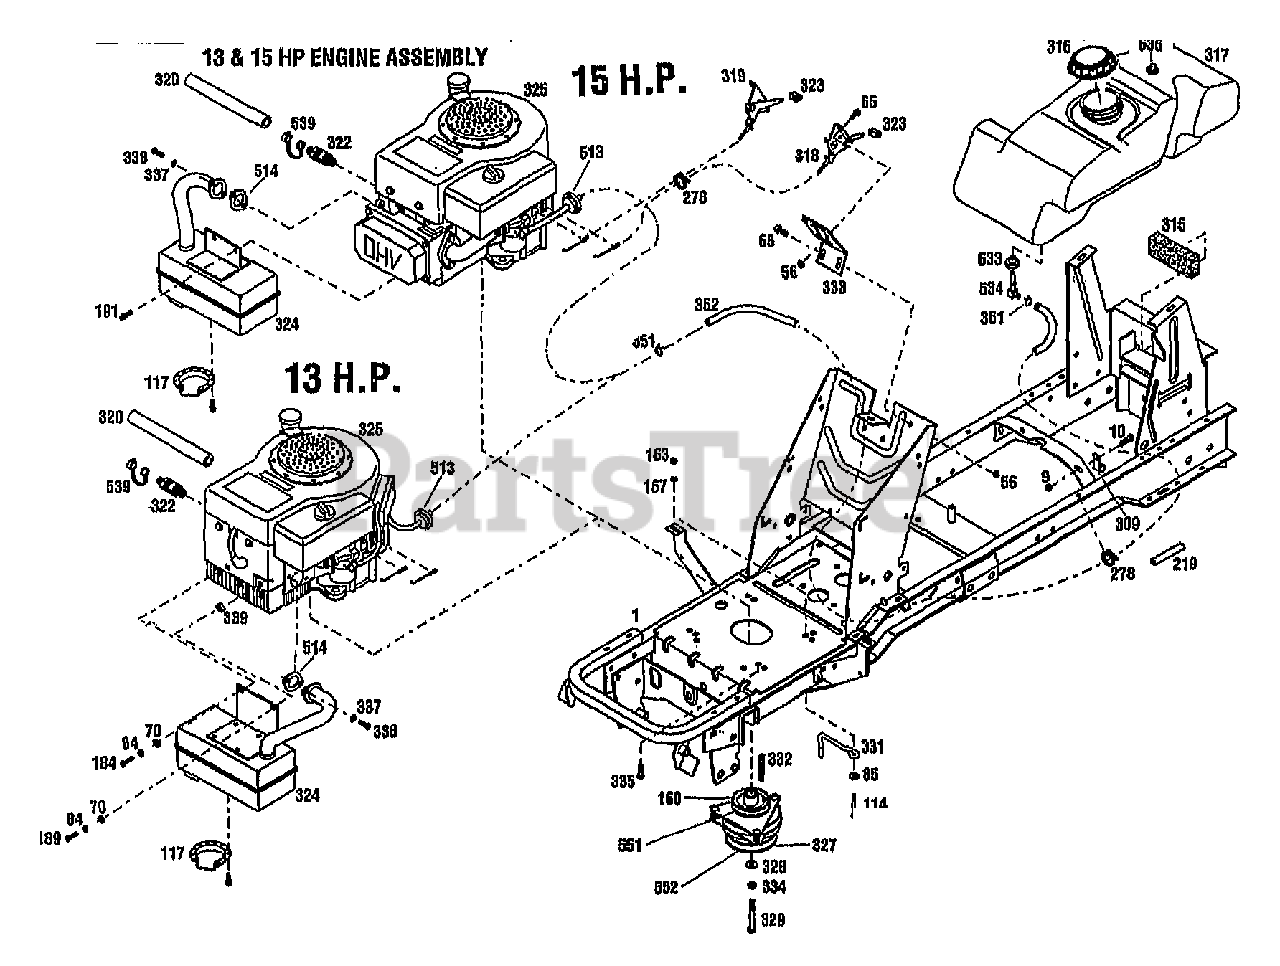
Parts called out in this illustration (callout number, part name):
1	ASSM-FRAME LTX
9	NUT-HFLK 5/16-18 ZP
10	SCR-HHC 5/16-18X.75 GR 5 ZP
56	NUT-HF/LK 1/4-20 ZP
65	SCR-HH 1/4-20X.625
70	WASHER-FLAT 1/4 SAE
84	WASHER-LK .25 ZP
85	WASHER-FLAT 3/8 SAE
114	SCR-THRD FRM 3/8-16X1.50
117	DEFLECTOR-MUFFLER
160	PULLEY-ENGINE
163	NUT-HEX 3/8-16 ZP
167	WASHER-LK .375 @ DEPL
184	SCR-HH 1/4-20 X .875
189	SCR-HH 1/4-20X1.25
191	SCR-FLANGE 1/4-20X3/4 GR5 {13086}
278	TIE-CABLE NYLON BLACK
309	CLIP-J
315	PAD-FUEL TANK
316	CAP-FUEL
317	TANK-FUEL
318	CONTROL-THROTTLE
319	CONTROL-CHOKE
320	HOSE-OIL DRAIN
322	ASSM-OIL VALVE
324	MUFFLER {13085}
324	MUFFLER {13086}
324	WASHER-LK .438 ZP
325	ENGINES, 13HP B&S 28M707-0615-A1 (13085)
325	ENGINES, 15HP B&S 28M707-0612-A1 (13086)
327	CLUTCH-ELECTRIC
328	WASHER-SPEC 1.42X.468X.25 ZP
329	SCR-HH 7/16-20X3.00
331	CLUTCH-RETAINER
332	KEY-.25 SQ X 2.5
333	BRKT-MOUNTING CONTROL
335	SCR-HH 3/8-16X1.0 THDFM
337	WASHER-LOCK
338	SCR-HXSKT 5/16-18X.75 BO
339	SPACER-.625X.344X.34 {13085}
351	CLAMP-HOSE
352	LINE-FUEL
513	FILTER-FUEL
514	MUFFLER GASKET
533	BUSHING-RUBBER
534	ELBOW-90 DEG (FUEL LINE)
535	VENT-FUEL TANK
539	CAP-OIL DRAIN
551	BEARING-UPPER CLUTCH
552	BEARING-CLUTCH LOWER
